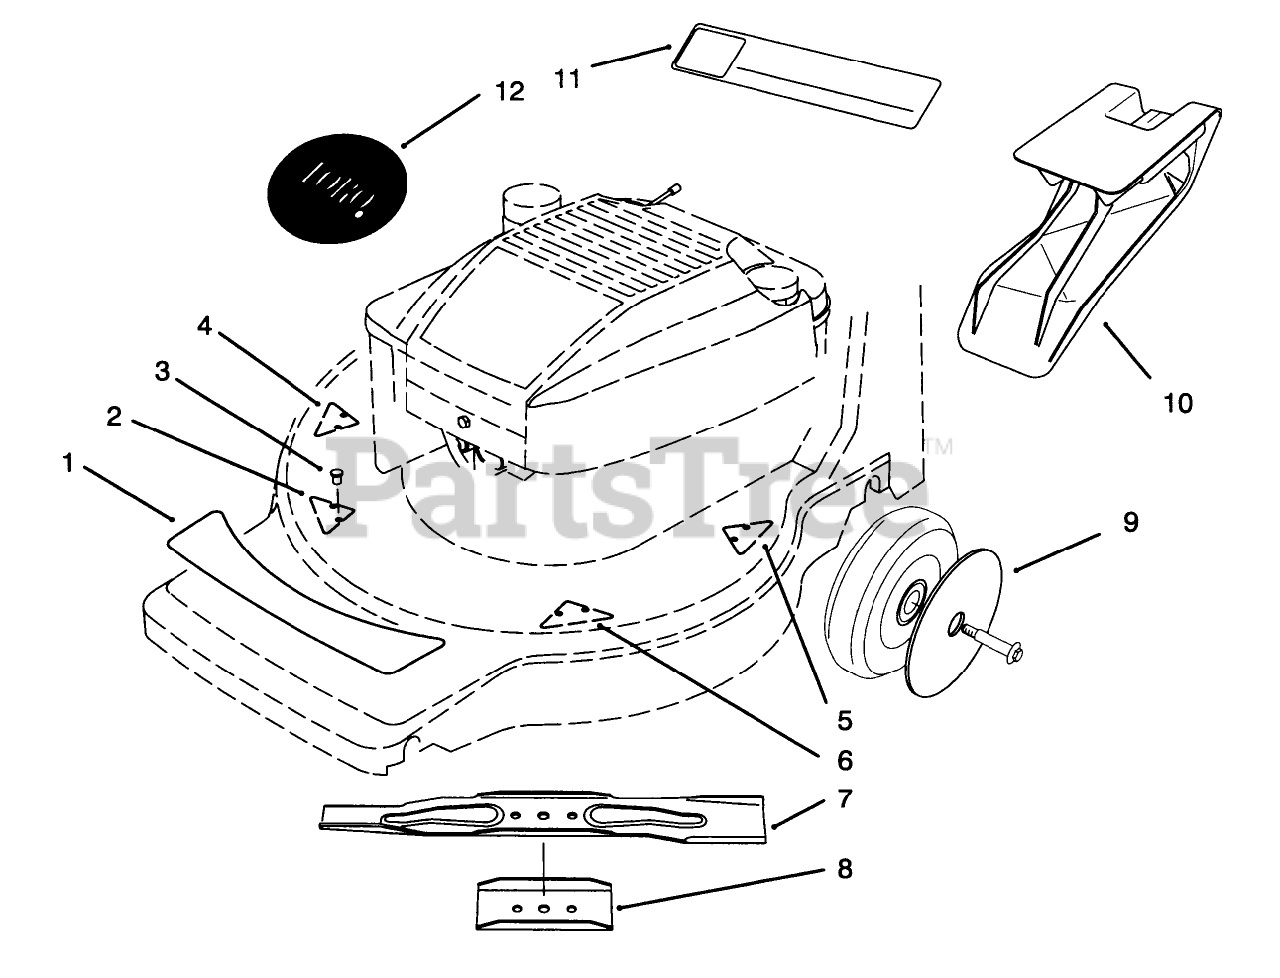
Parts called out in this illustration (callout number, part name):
1	DECAL - DECK
2	KICKER
3	SCREW-PPH
4	KICKER
5	KICKER
6	KICKER
7	Blade
8	Stiffener
9	COVER-WHEEL
10	DISCHARGE PLUG
11	DECAL - PANEL
12	DECAL - ENGINE
